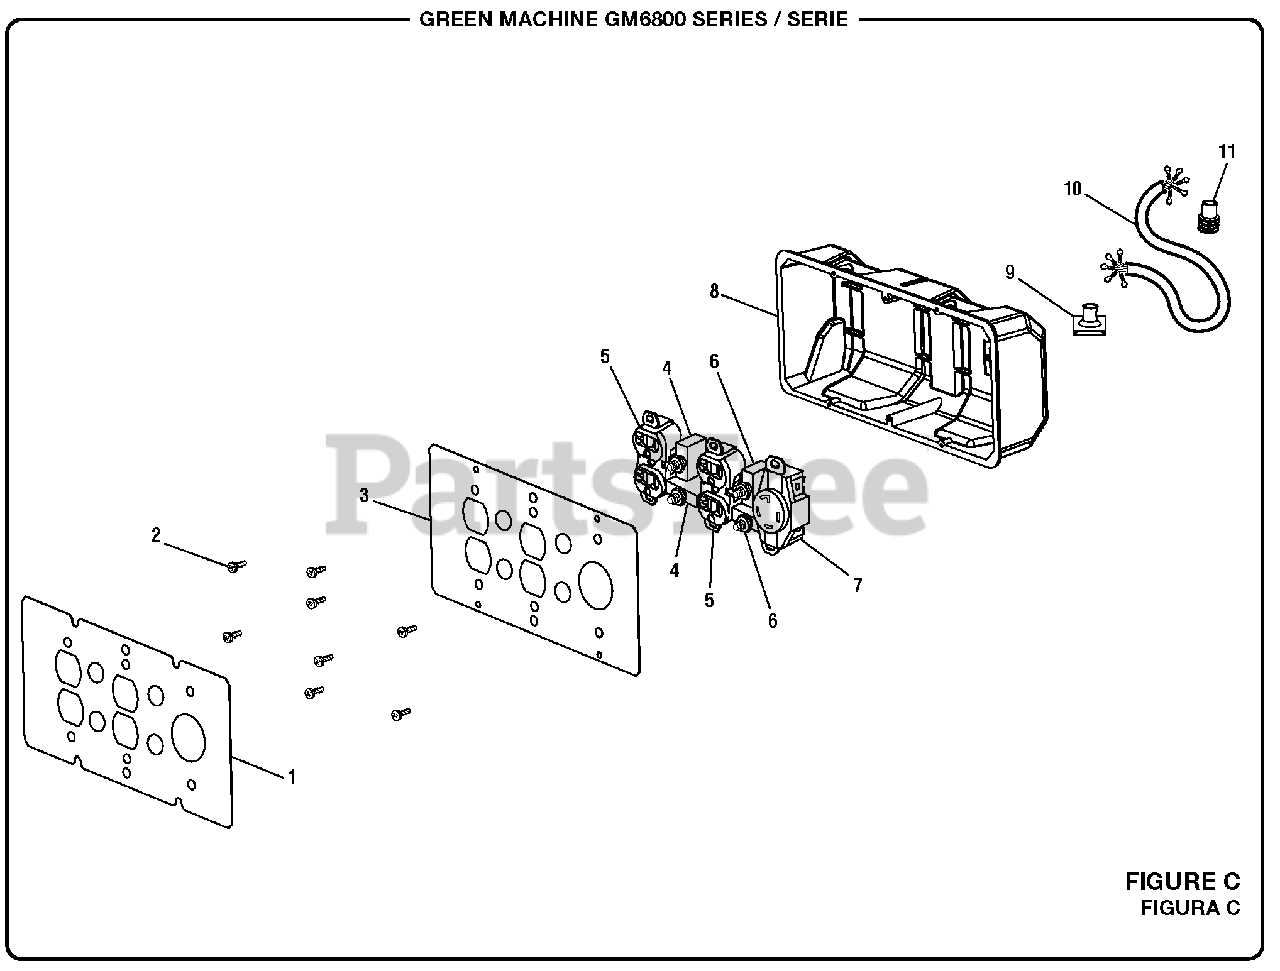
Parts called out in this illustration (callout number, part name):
1	Label (Power Outlet)
2	Screw (6-20 x 3/8 in.)
3	Front Panel
4	Circuit Breaker (20 Amp, 125 Volt)
5	120 Volt Duplex Receptacle
6	Circuit Breaker (30 Amp)
7	Twist Lock Receptacle (120/240 Volt, 30 Amp, L14-30R)
8	Control Box (Back Panel)
9	Rubber Boot (Control Panel Assembly)
10	Wiring Harness
11	Rubber Boot
